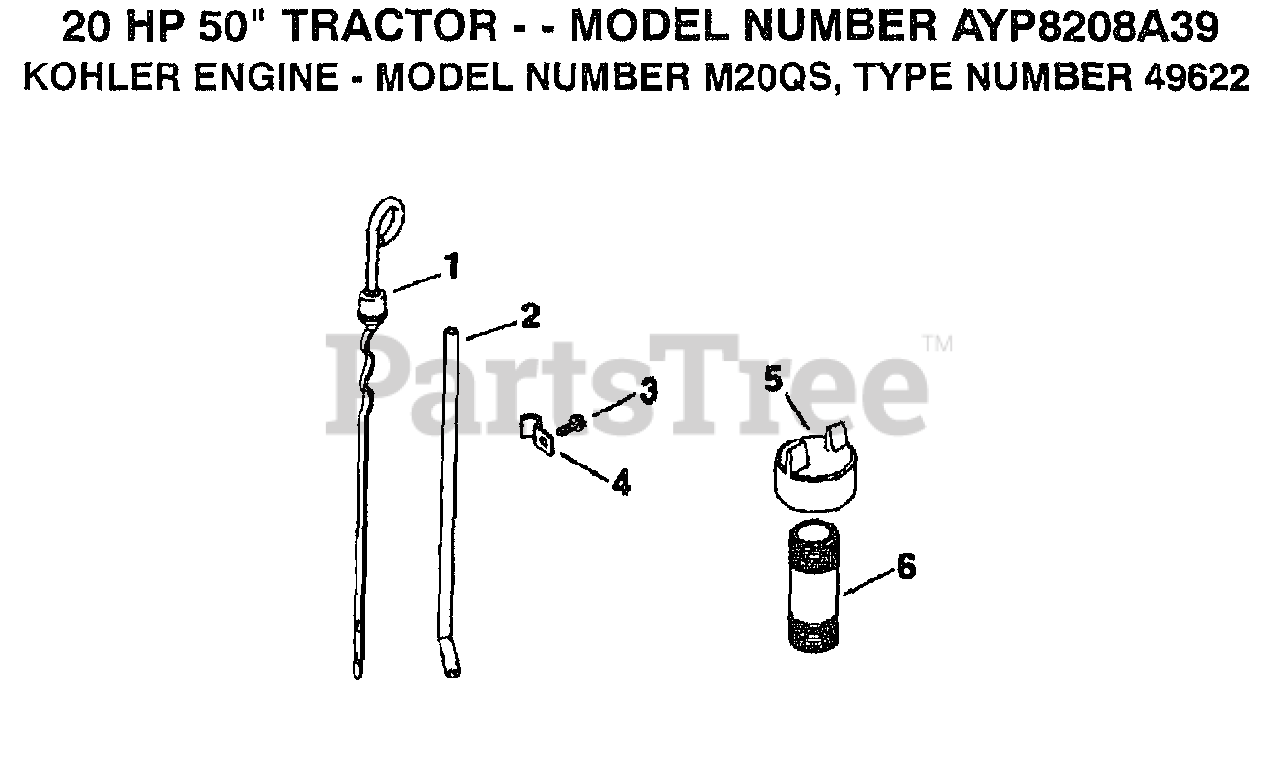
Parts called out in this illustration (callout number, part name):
1	DIPSTICK, BLADE
2	TUBE, OIL LEVEL
3	SCREW
6	PIPE, OIL FILL
